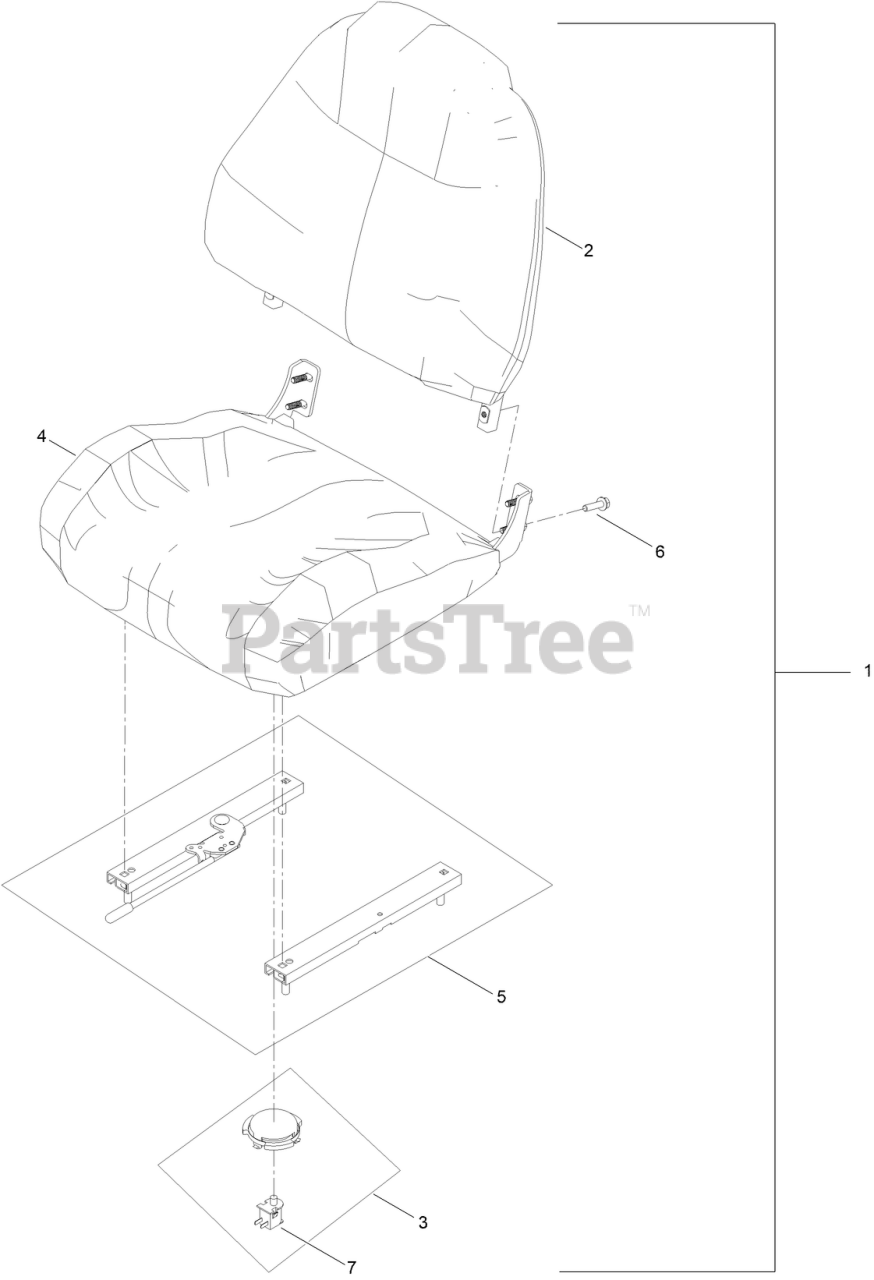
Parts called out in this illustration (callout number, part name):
1	SEAT ASM
2	TORO BACK COVER
3	SEAT SWITCH DELTA 6500-02 OPEN
4	TORO SEAT COVER
5	SLIDE ASM-SEAT
6	SCREW-HHF
7	SWITCH-BAIL
